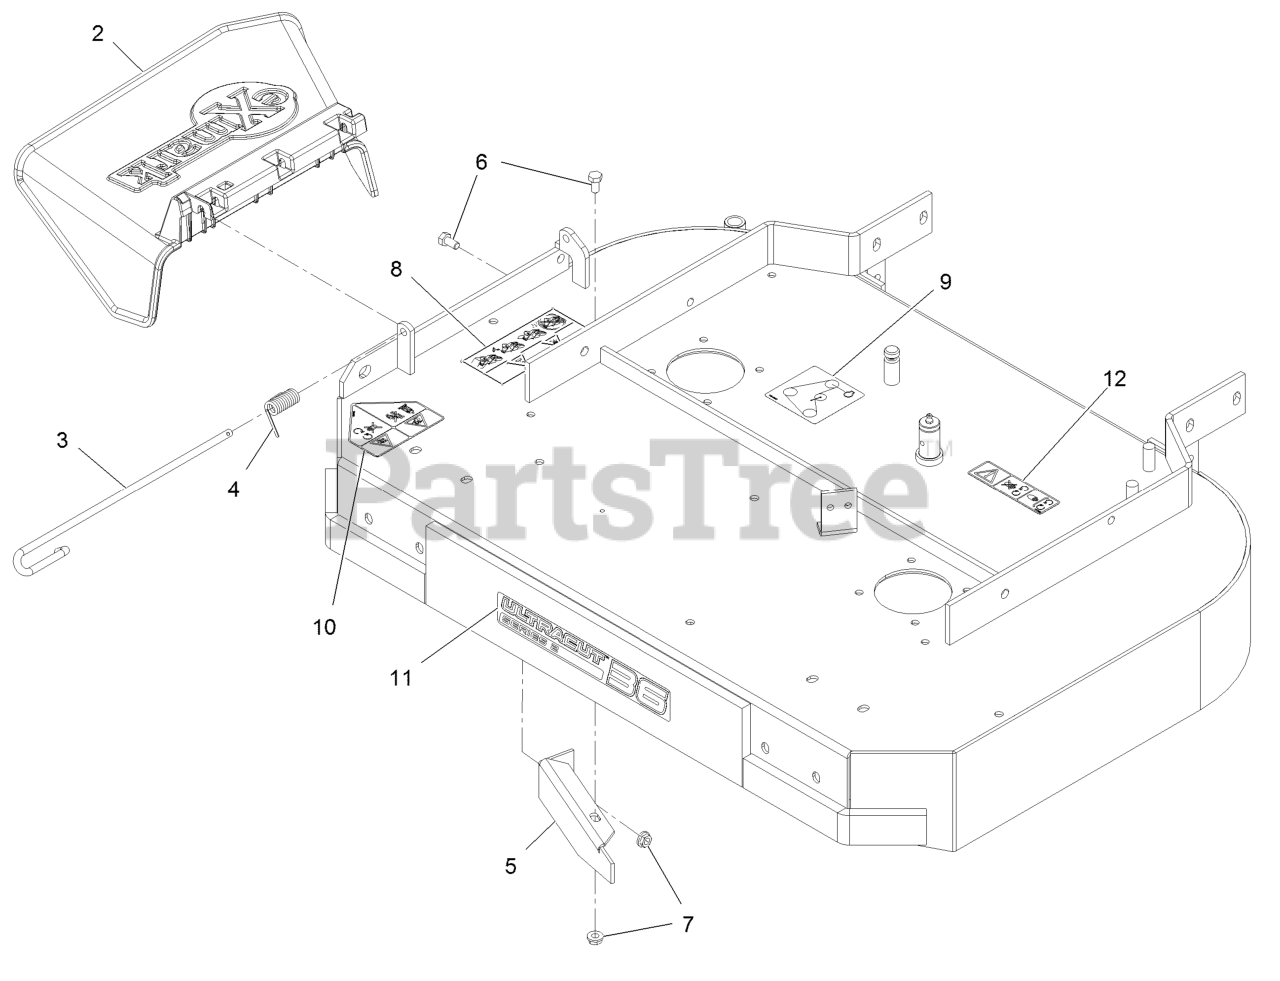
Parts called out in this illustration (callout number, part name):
2	Deflector-Discharge
3	Pin-Chute
4	Spring, Torsion
5	Baffle-Dogleg
6	Screw-HH 5/16-18 X 5/8
7	Nut-Whizlock 5/16-18
8	Decal-Warning, Bagger
9	Decal-Belt Routing 32-36
10	Decal-Danger
11	Decal-Ultracut 36 Series 2
12	Decal-Cover, Missing
